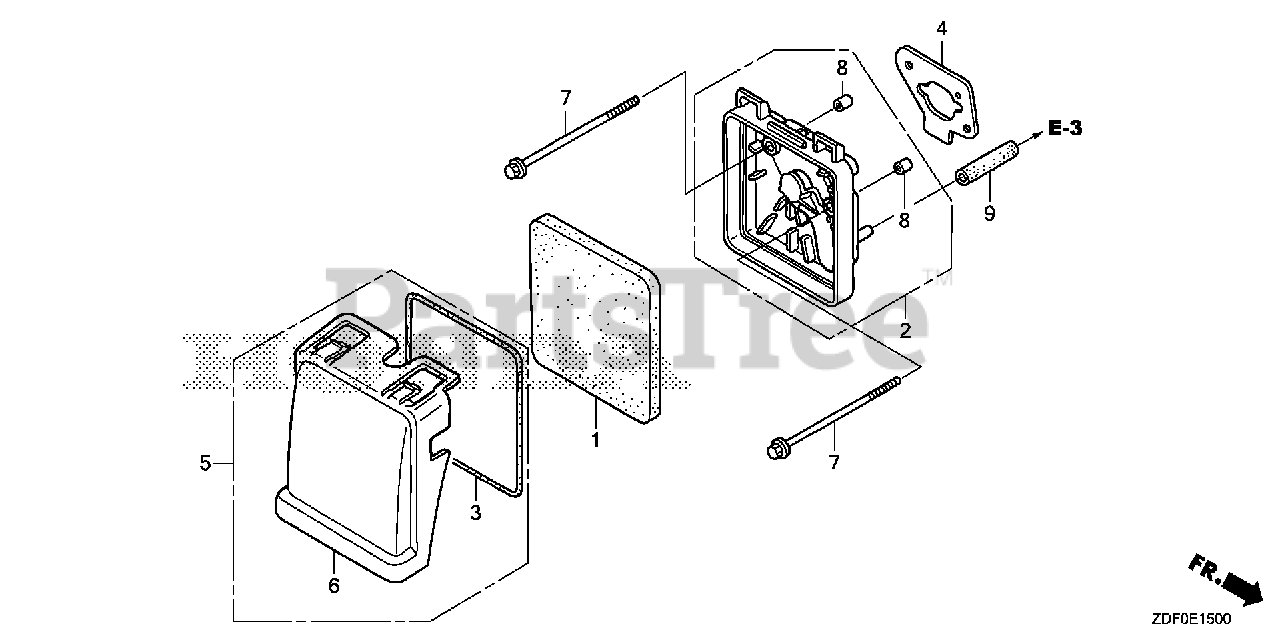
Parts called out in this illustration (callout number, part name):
1	ELEMENT, AIR CLEANER
2	HOUSING, AIR CLEANER
3	SEAL, AIR CLEANER
5	COVER, AIR CLEANER
6	COVER, AIR CLEANER
7	BOLT, FLANGE (5X75)
8	COLLAR, AIR CLEANER
9	BULK HOSE, VACUUM (7X3000) (7X550)
